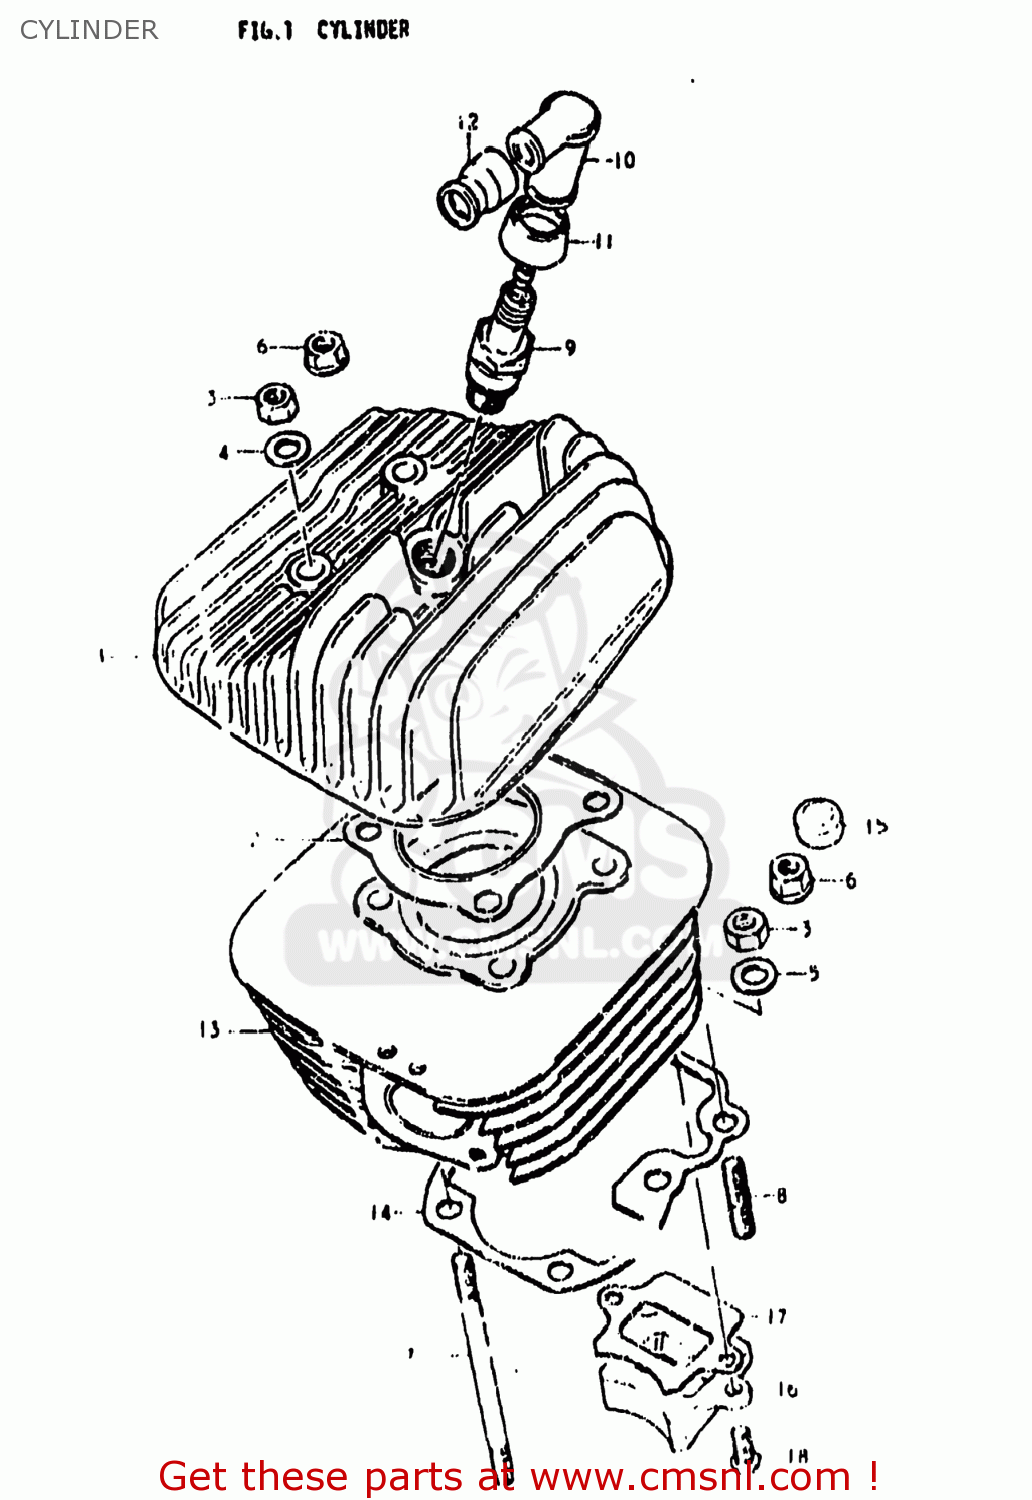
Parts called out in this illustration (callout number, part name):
1	HEAD,CYLINDER
2	GASKET,CYLINDER HEAD (NAS)
3	NUT
4	WASHER
5	WASHER
6	NUT
7	BOLT,STUD
8	STUD 8X20
9	SPARK PLUG
10	CAP,SPARK PLUG
11	SEAL,SPARK PLUG
12	SEAL,SPARK PLU
13	CYLINDER
14	GASKET,CYLINDER
15	PAD,CYLINDER
16	VALVE ASSEMBLY,REED
17	GASKET,REED VALVE (MCA)
18	SCREW
